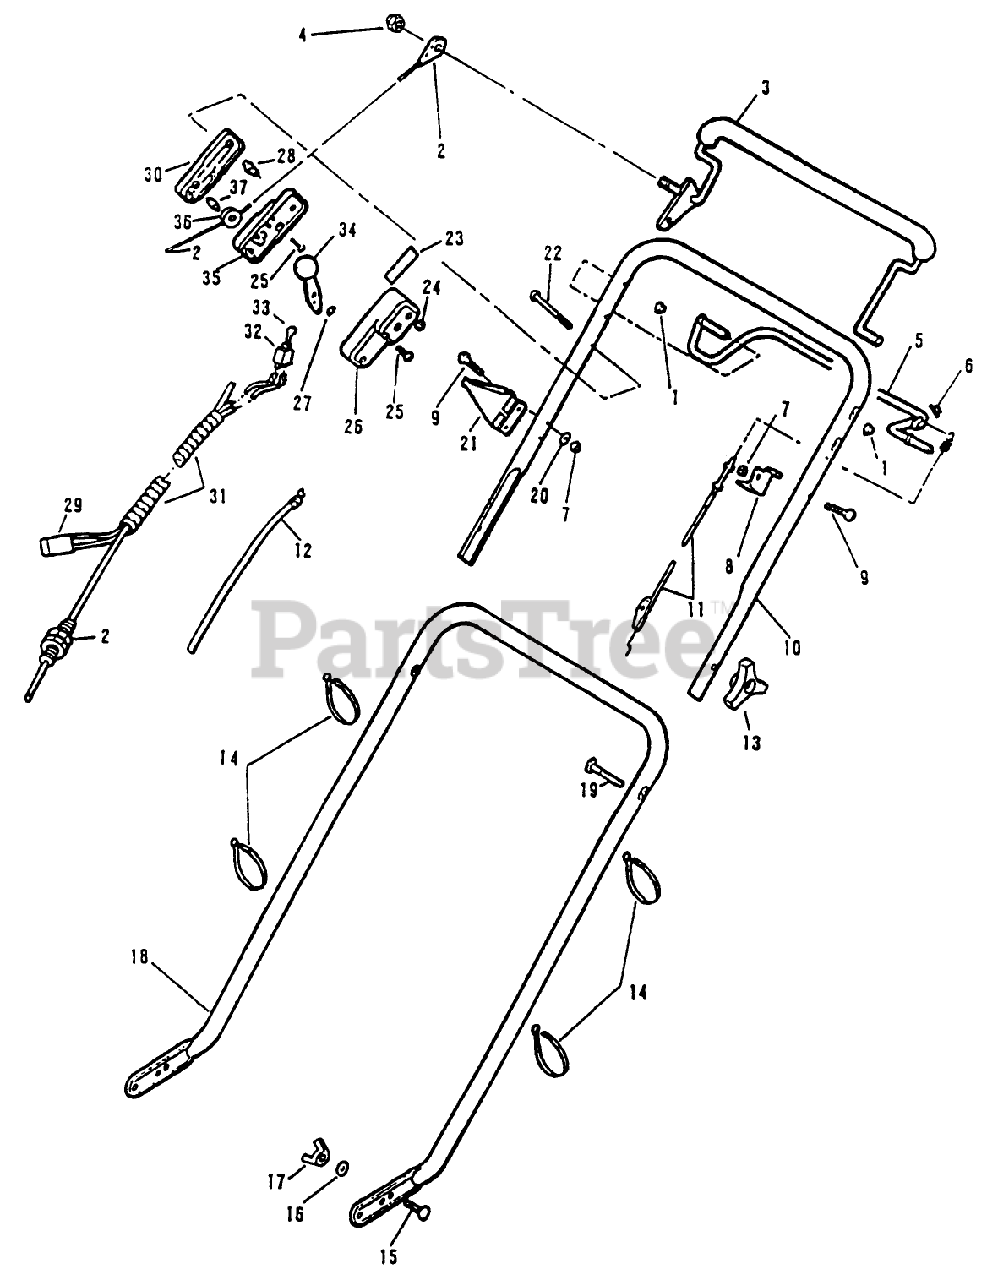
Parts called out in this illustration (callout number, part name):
2	CONTROL CABLE
3	CONTROL LEVER ARG
4	NUT ACORN
7	LOCKNUT E
8	ANCHOR C'DUIT TRO
11	CABLE - CONTROL
12	CABLE TH'TTLE WES
14	TIE-CABLE
17	NUT WING
20	WASHER
22	SCREW
24	NUT C/LOCK E
25	SCREW
26	CASE THROTTLE
27	WASHER-SPRING
28	COLUMN
30	OUTER CONTROL CASE
34	LEVER&KNOB AY WES
36	PULLEY PL
37	PIN SKF
